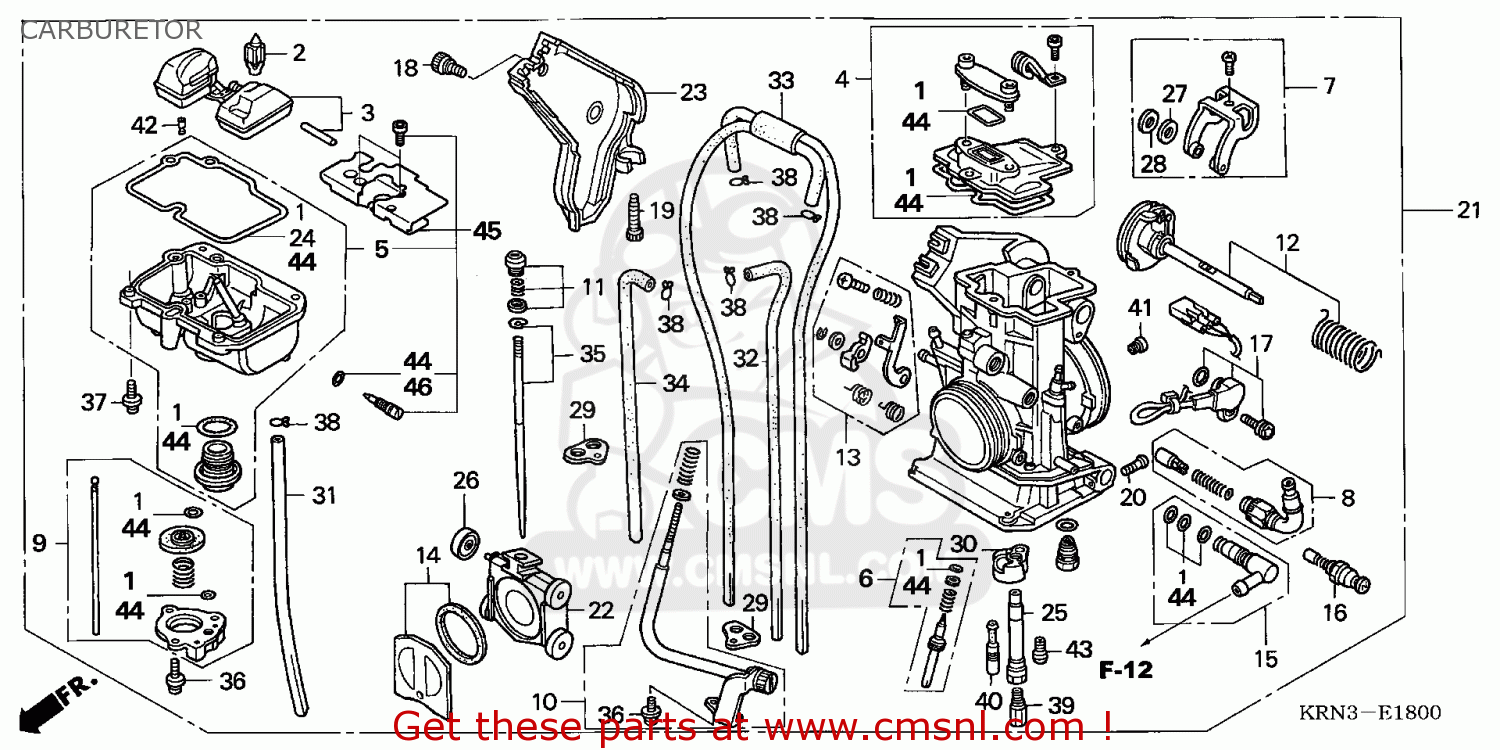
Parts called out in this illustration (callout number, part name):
1	GASKET SET
2	VALVE SET,FLOAT
3	FLOAT SET
4	TOP SET
5	CHAMBER SET,FLOAT
6	SCREW SET,A
7	ARM SET,LINK
8	HOT START SET
9	PUMP DIAPHRAGM SE
10	SCREW SET B
11	NEEDLE SCREW SET,
12	SHAFT COMP SET,TH
13	LEVER SET,PUMP
14	FLOTING VALVE SET
15	FUEL JOINT SET
16	VALVE COMP,STARTE
17	SENSOR ASSY,TH.
18	BOLT,COVER
19	BOLT,STOPPER
20	SCREW,PAN
21	CARBURETOR ASSY
22	VALVE,THROTTLE
23	COVER,THROTTLE
24	GASKET,FLOAT CHAM
25	HOLDER,NEEDLE JET
26	ROLLER
27	WASHER PLAIN A(PO
28	WASHER PLAIN B(SU
29	BINDER
30	PLATE,BUFFER
31	TUBE(OF)
32	TUBE(AV)
33	TUBE COMP(AV)
34	TUBE(AV)
35	NEEDLE SET,JET
36	SCREW-WASH.,4X8
37	SCREW-WASHER,4X14
38	CLIP B1 7,TUBE
39	JET,MAIN,#162
40	JET,SLOW,#38
41	JET,SLOW AIR
42	LEAK JET,ACCP
43	JET,BY-ST # 68
